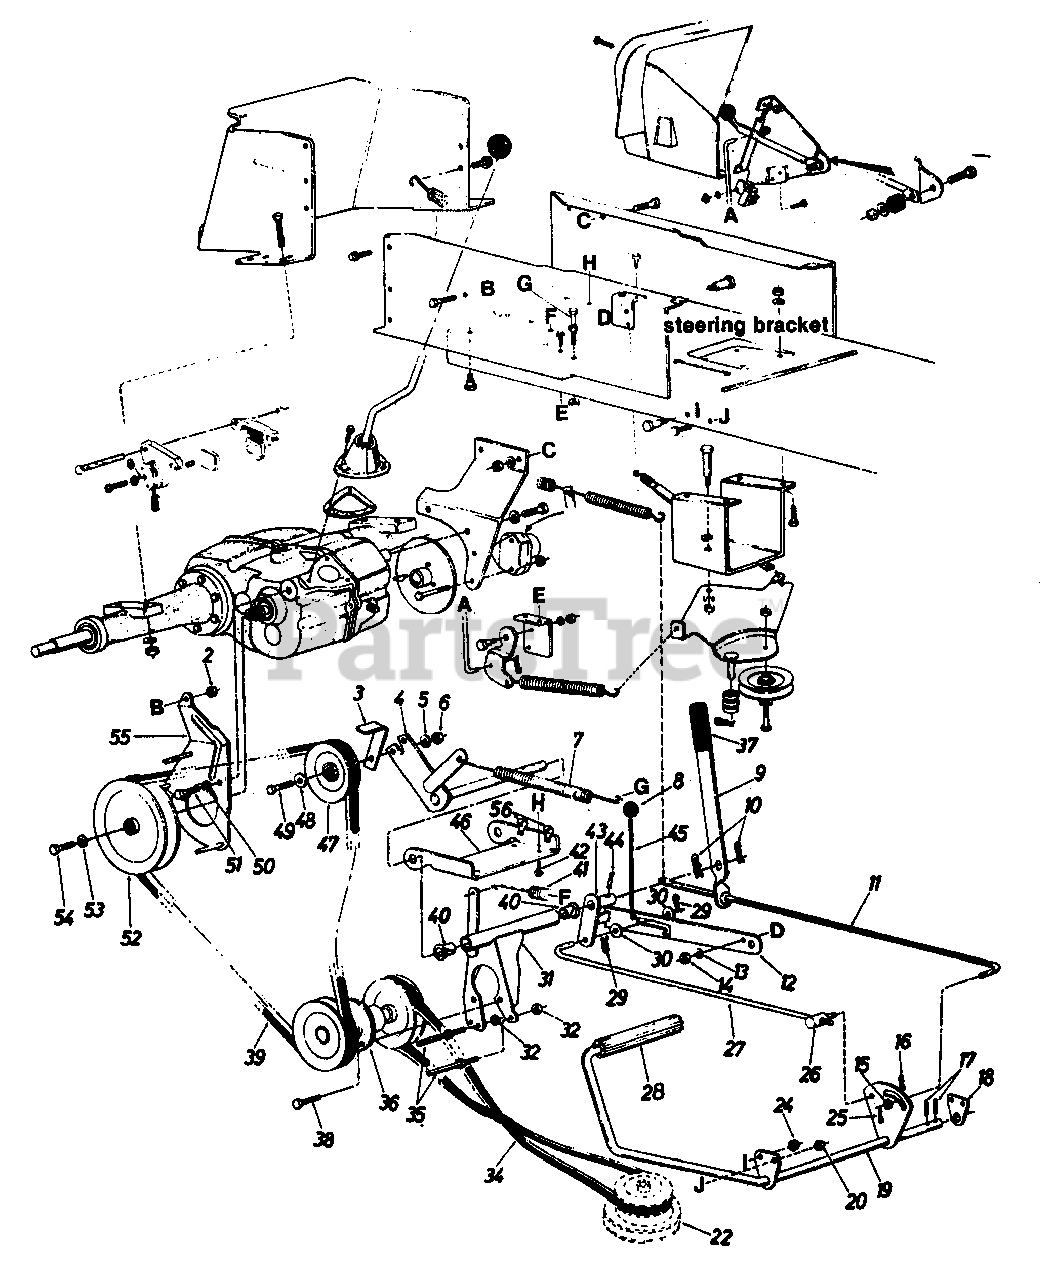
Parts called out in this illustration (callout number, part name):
2	Hex L-Nut 3/8-16 Thd.
5	L-Wash. 3/8" Scr.*
6	Hex Nut 3/8-16 Thd.*
7	Ext. Spring
8	Knob
9	Hand Brake Lever
10	Hairpin Cotter 5/8" Dia.
11	Brake Rod
12	Parking Brake Cam
13	Fl-Wash. 5/16" Scr.
14	Hex Nut 5/16-18 Thd.*
15	Fl-Wash. 5/16 Scr.
16	Hairpin Cotter 3/8" Rod
17	Cotter Pin 1/8" Dia. x 1.00" Lg.*
18	Clutch Rod Brg. Brkt.
19	Clutch Brake Pedal Ass'y.
20	Hex Cent. L-Nut 3/8-16 Thd.*
22	Engine Pulley 4.75 & 5.56
24	Hex Cent. L-Nut 3/8-16 Thd.*
25	Cotter Pin 3/32" Dia. x .75" Lg.*
26	Pivot Bushing
27	Brake Cam Rod
28	Foot Pad
29	Hairpin Cotter 3/8" Rod
30	Fl-Wash. 3/8" I.D. x 1.00" O.D. x .030
31	Jack Shaft Mtg. Brkt. Ass'y.
32	Hex Top L-Nut 3/8-16 Thd.
34	"V"-Belt 1/2 x 59" Lg. (Polyester)
35	Stud 3/8-16 x 3.62" Lg. Special
36	Jack Shaft Ass'y.
38	Hex Sem Scr. 5/16-18 x .75" Lg.*
39	"V"-Belt 1/2 x 40" Lg. (Kevlar)
40	Nyliner 5/8" I.D. x .88" Lg.
41	Ext. Spring
42	Hex Thd. Rolling Scr. 1/4-20 x .50" Lg.
43	Clutch-ldler Horn Ass'y.
44	Spring Pin Spiral 1/4" Dia. x 1.00" Lg.
45	Parking Brake Link
46	Idler Mtg. Brkt. Drive
47	4" "V"-ldler Pulley
48	Fl-Wash. 3/8" I.D.
49	Hex Scr. 3/8-16 x 1.75" Lg.*
50	L-Wash. 3/8" Scr.*
51	Hex Scr. 3/8-16 x .75" Lg.*
52	"V"-Pulley 7.0" O.D.
53	L-Wash. 3/8" Scr.*
54	Hex Scr. 3/8-24 x .75" Lg.*
55	Belt Guard Ass'y.
56	Plastic Hose Clamp
